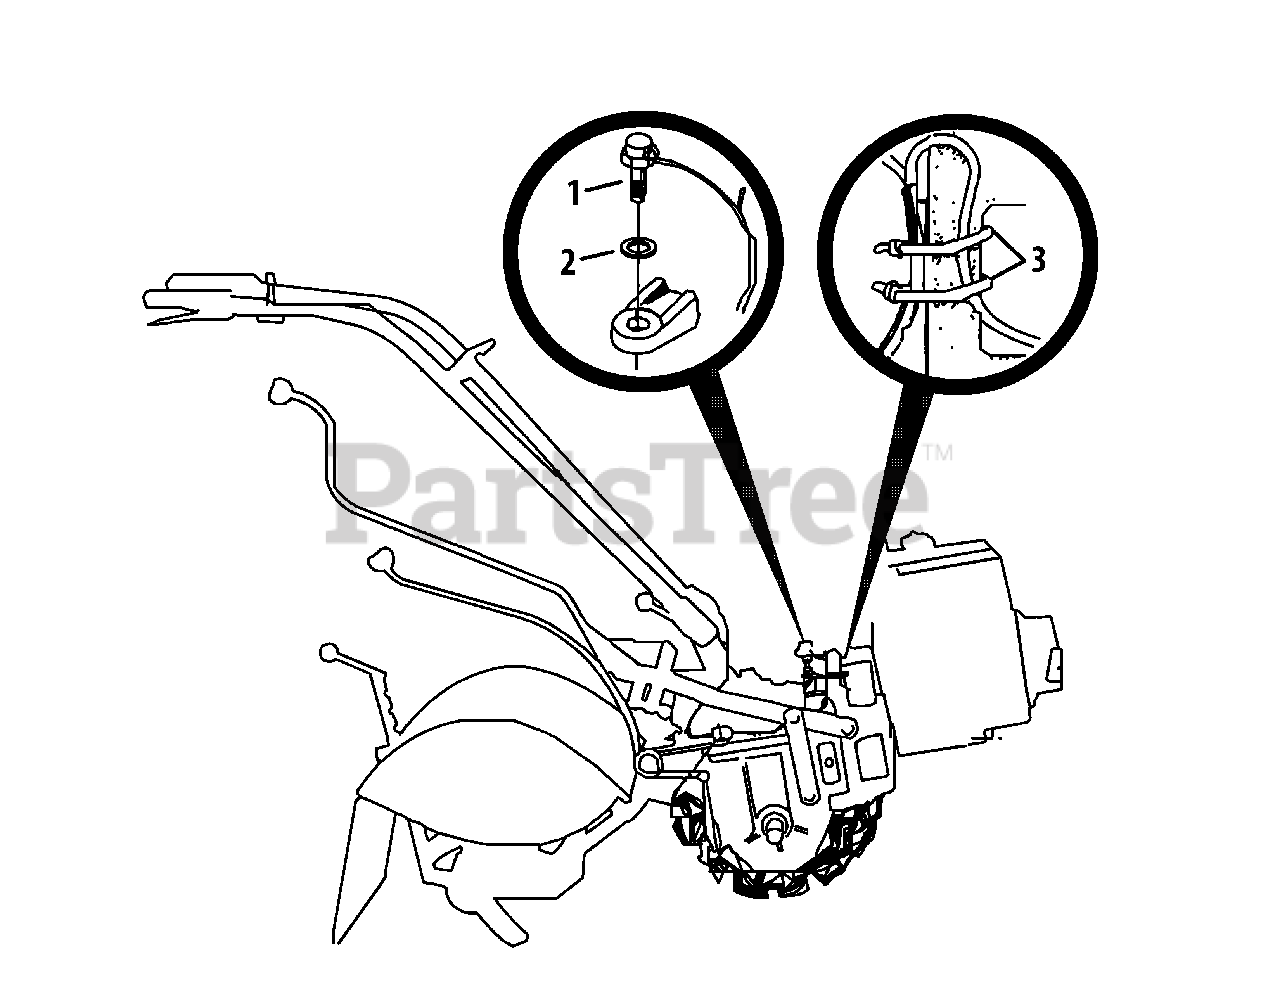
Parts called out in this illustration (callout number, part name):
1	PTO Switch
2	Internal L-Washer, 9/16"
3	Plastic Tie
